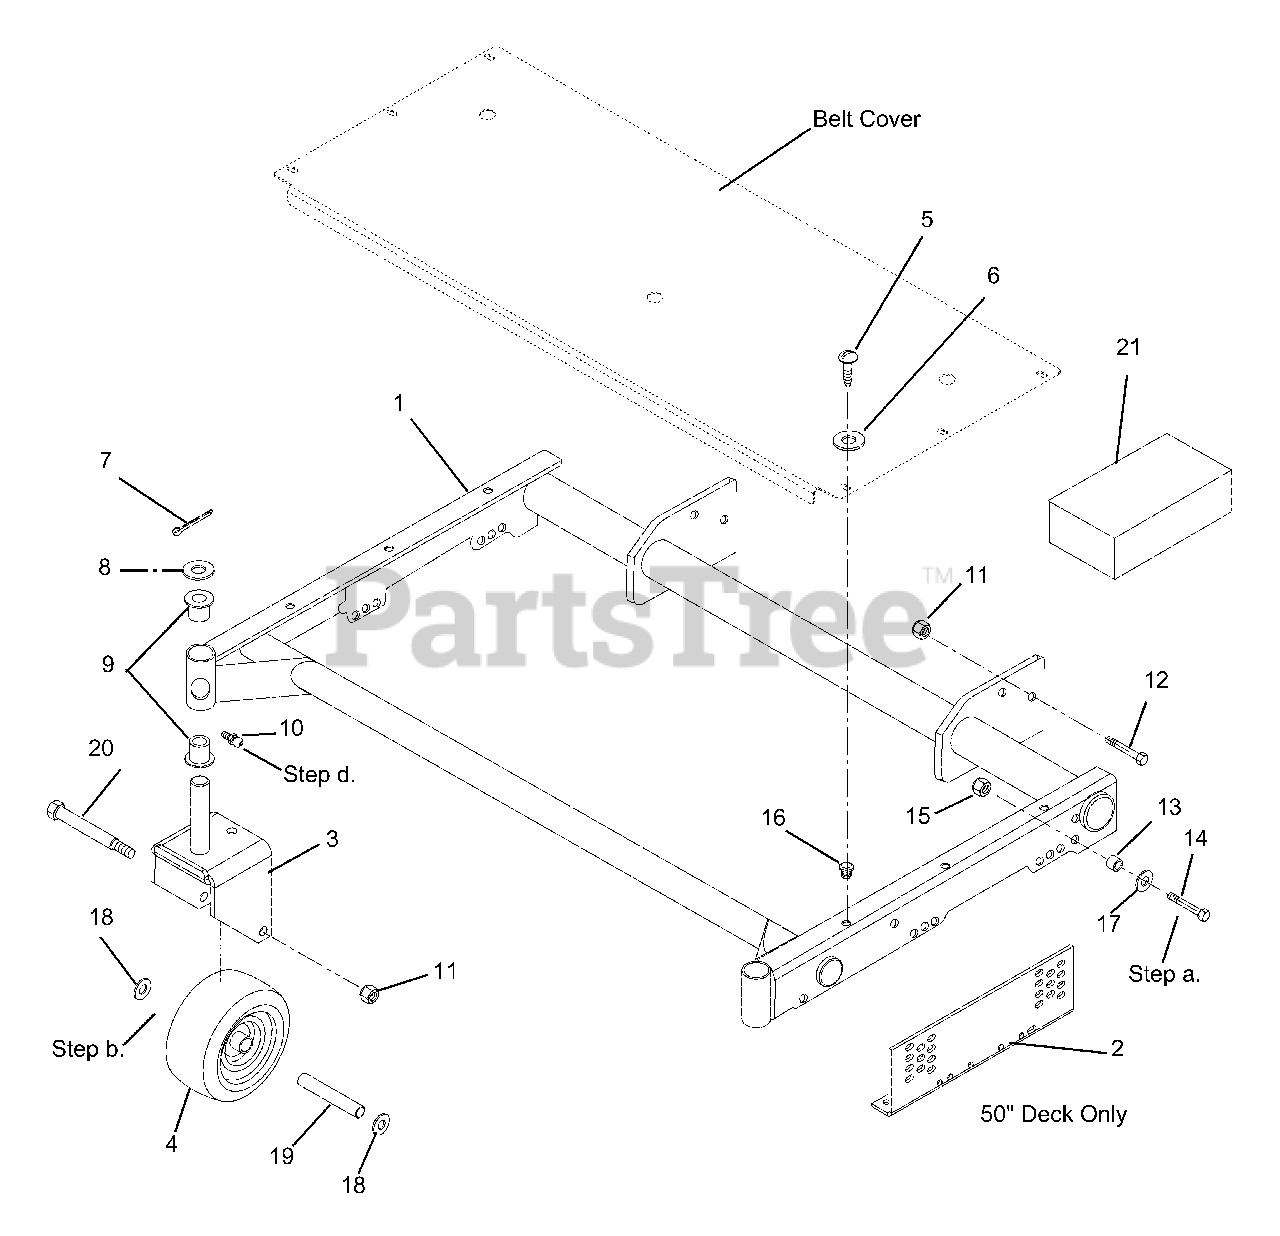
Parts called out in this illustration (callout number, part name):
1	Frame, 50" (59002600)
1	Frame, 60" (59002500)
2	Bracket, Side 50" RH (59002600)
2	Bracket, Side 50" LH (59002600)
3	Weldment, Caster Fork
4	Wheel, Assembly 9.00 x 3.5
5	Screw, Tapping .25-20 x .50
6	Washer, Flat .28 x .62 x .065
7	PIn-Cotter .18 x 1.5
8	Washer, Hardened 1.0 x .55 x .03
9	Bushing, Flange .02 x 1.38 x .75
10	Fitting, Lube
11	Nut, Locking Nylon .50-13
12	Bolt, Hex .50-13 x 1.50
13	Bushing .39 x .62 x .67
14	Bolt, Hex .38-16 x 1.50
15	Nut, Locking Nylon .38-16
16	Grommet, Plastic
17	Washer, Flat .39 x 1.5 x .125
18	Washer, Hardened .76 x .25 x .09
19	Bearing .75 x .53 x 3.97
20	Bolt, Hex .50-13 x 5.50
21	Promaster 300 Tractor Idler Kit
